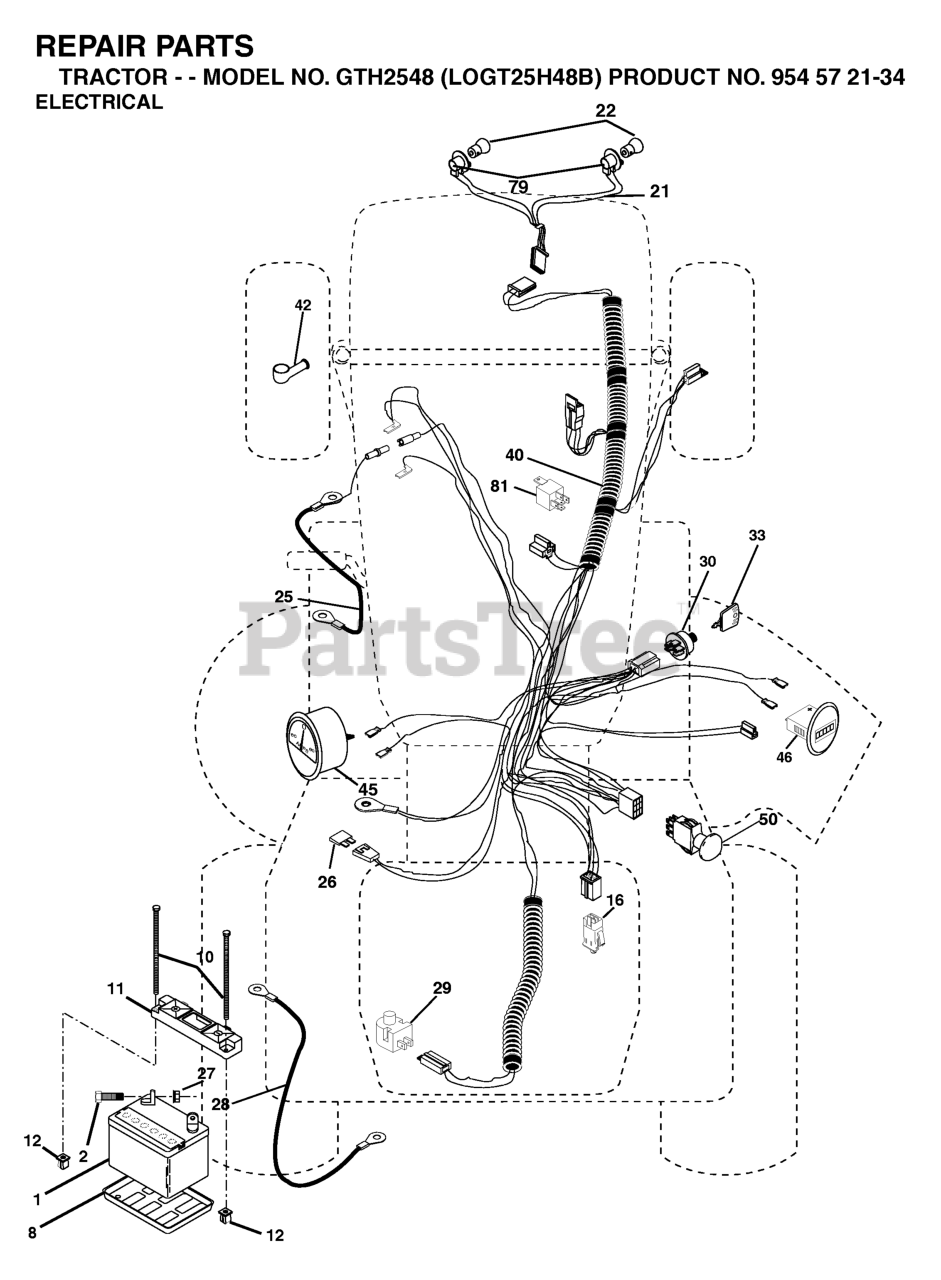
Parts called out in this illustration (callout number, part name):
1	BATTERY 12V .35 AMP
2	BOLT.HEX.1/4.X.3/4.DICHROMATE
8	BATTERY TRAY T
10	BOLT 1/4-20 X 7.5
11	BATTERY HOLDDOWN FRONT MOUNT
12	NUT, PUSH NYLON 1/4" BATTERY
16	SWITCH INTERLOOK PUSH-IN
21	HARNESS.W/LIGHT SOCKET
27	NUT
28	CABLE, GROUND
29	RP.SWITCH.PLUNGER.NC.GRAY
33	KEY MLD GEN DELTA
40	HARNESS.IGNITION.VGT.NO.RELAY
42	COVER.TERMINAL.RED
45	RP AMMETER.ROUND.SILVER.DELTA
46	RP HOURMETER SNAP-IN
50	RP.PTO.SWITCH.8 TERMINAL.BLACK
79	BULB HOLDER ASM.
81	RELAY.ASSY.T
